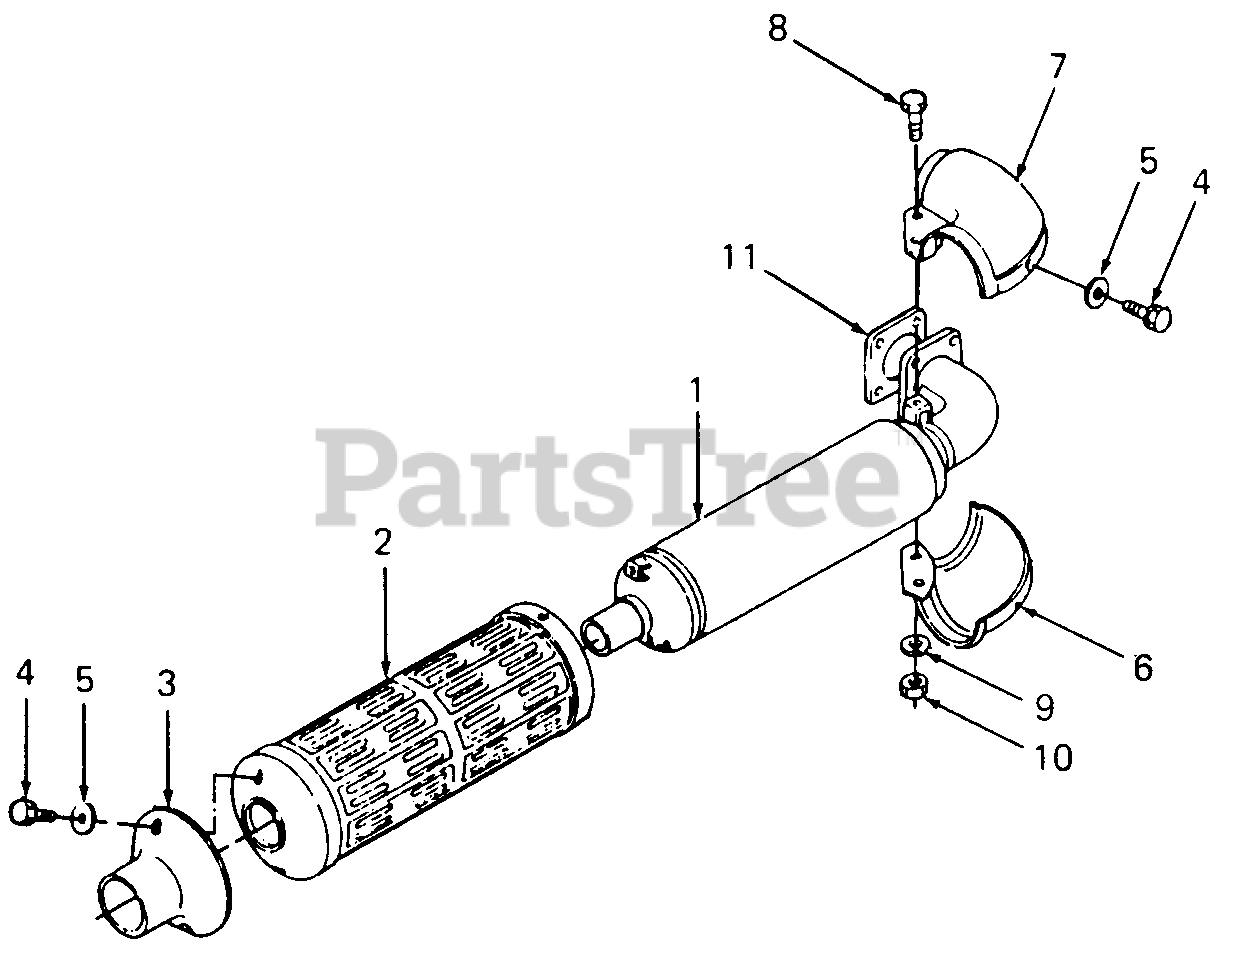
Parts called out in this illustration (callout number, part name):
2	Cover, Muffler
3	Cover, Muffler Pipe
5	Washer, Plain
6	Cover, Muffler Flange
7	Cover w/Nut, Muffler Flange
8	Bolt
9	Washer, Spring
11	Gasket, Muffler
